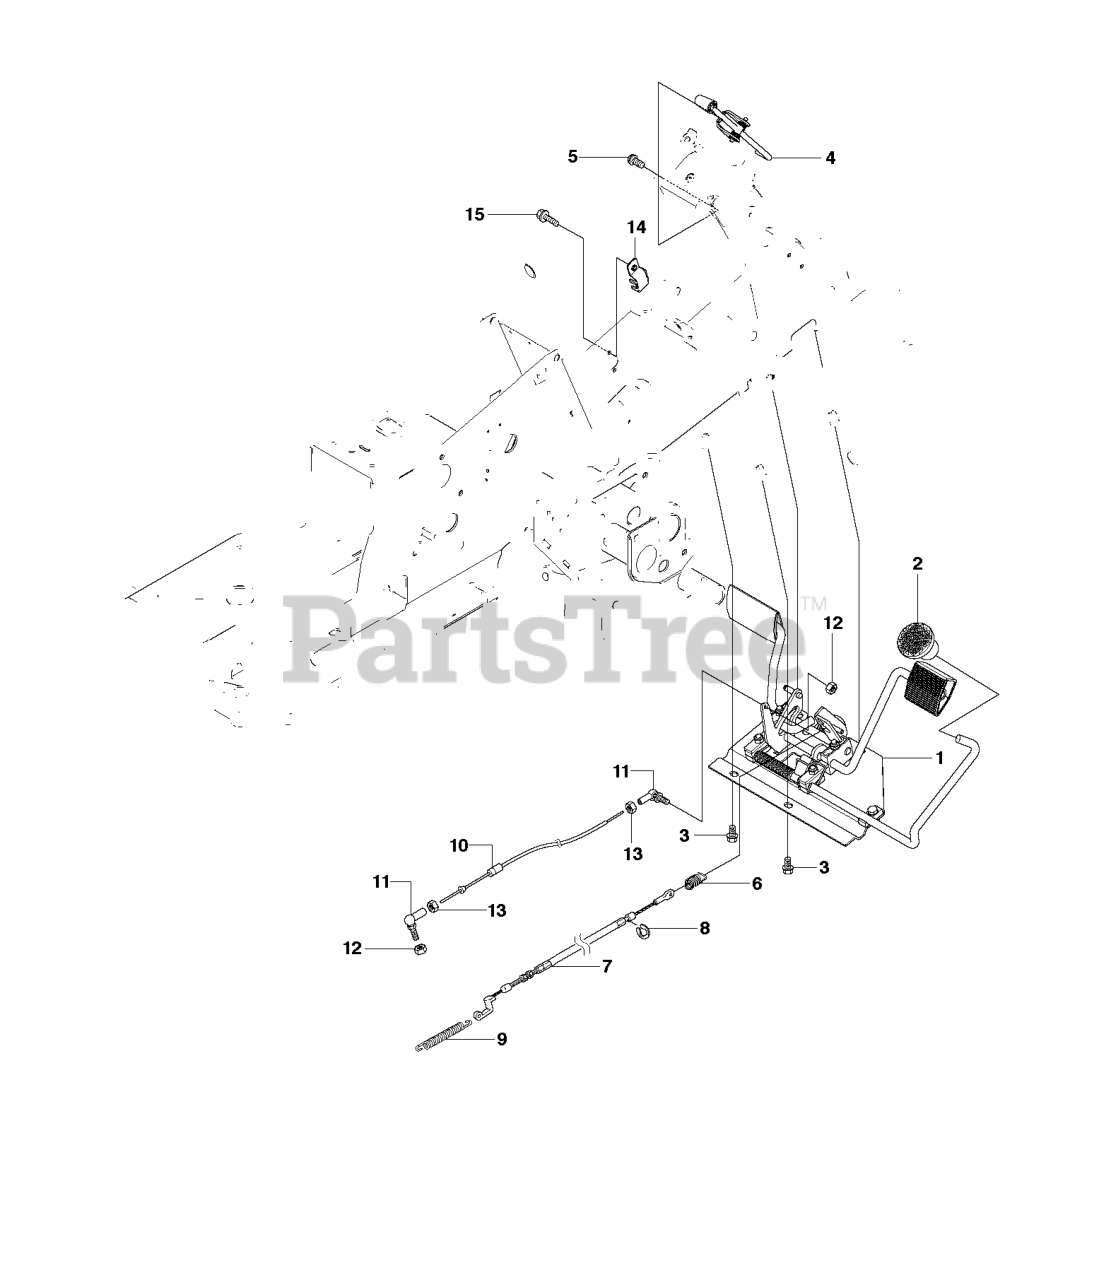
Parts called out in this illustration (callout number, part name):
1	PEDAL ASSEMBLY
2	KNOB
4	BRAKE LEVER ASSY
7	BRAKE WIRE
10	CONTROL CABLE
11	CONNECTOR
12	LOCKNUT M5
